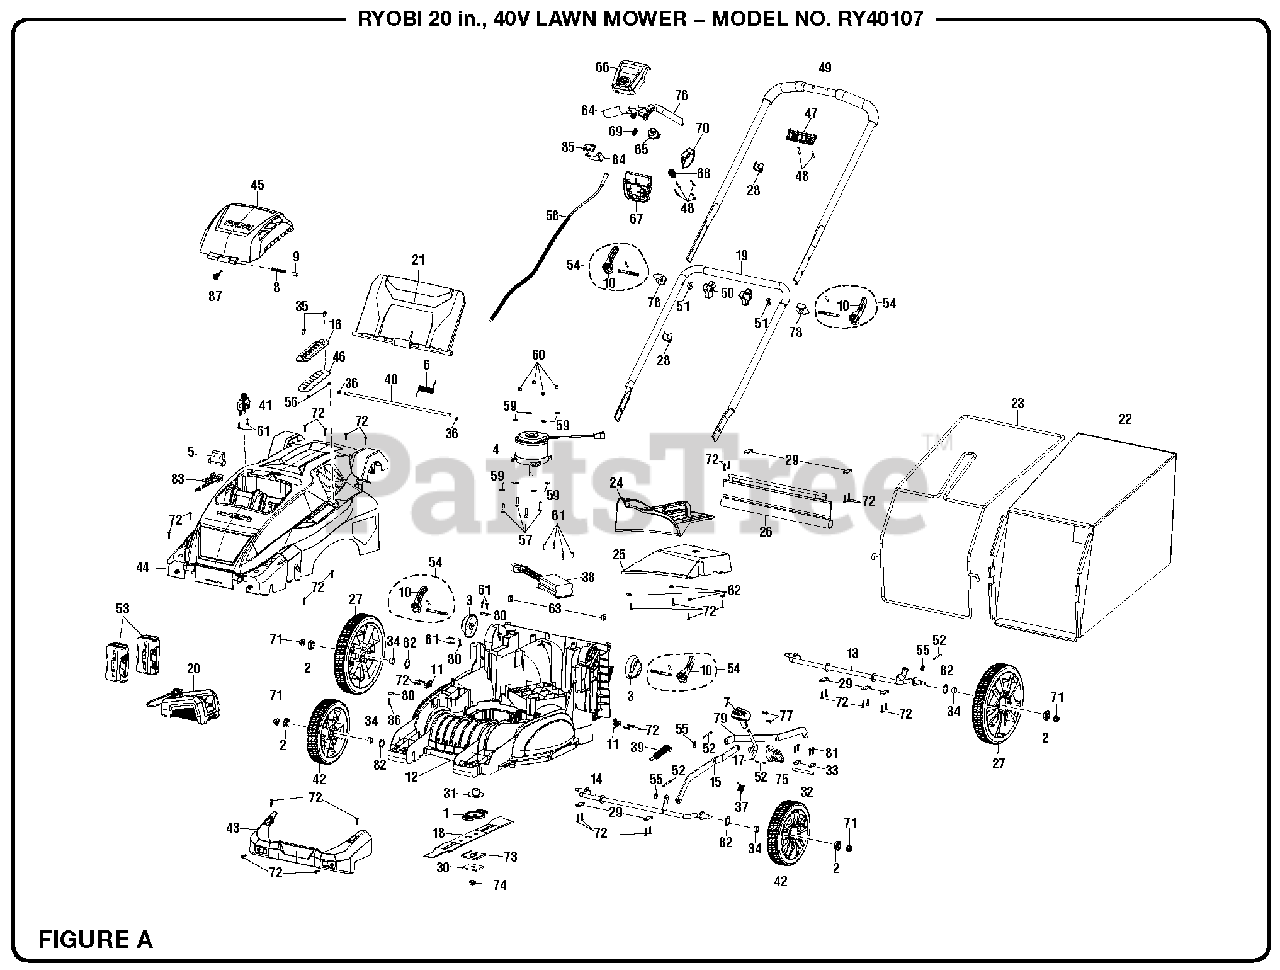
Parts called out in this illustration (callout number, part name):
1	Blade Holder
2	Flanged Outer Ring Bearing
3	Quick Lock Press Block
5	Base (Battery Connect)
6	Torsion Spring (Rear Door)
7	Adjust Height Handle
10	Adjust Height Handle
11	Axle Mount
12	Deck (20 in)
13	Rear Wheel Axle
14	Front Wheel Axle
15	Forward Linkage
16	Lift Arm Bracket
18	Blade
19	Lower Handle
20	Charger
21	Rear Door
23	Bag Frame
24	Mulching Plug
26	Rear Protective Guard
27	Rear Wheel (10 in)
28	Cord Clamp
29	Axle Press Plate
30	Metal Blade Retainer
31	Motor Shaft Bushing
32	Adjust Height Axle
33	Adjust Height Press Plate
34	Bearing Sleeve
35	Screw (M5 x 16 mm, Phillips Pan Hd)
36	Retaining Ring (E)
37	Torsion Spring (Height Adjustment)
38	Electical Control Panel Assembly
39	Retention Spring
40	Rear Door Axle
42	Front Wheel (8 in)
44	Deck Cover
45	Battery Cover
46	Shifter Boot
47	Lower Front Control
48	Screw (M4 x 30 mm, T15 Torx Pan Hd)
49	Handle Assembly Upper
52	Cotter Pin
53	Battery
54	Handle Lock Assembly
55	Washer (ID84 x OD18 x 1t)
56	Hex Nut (M5)
57	Bolt (M6 x 26 mm, Hex Hd)
58	Starter Cable
59	Washer (ID15 x OD62 x 08t)
60	Hex Nut (M6)
61	Screw (M4 x 16mm, T20 Torx Hd)
62	Washer (ID45 x OD10 x 1t)
63	Square Nut (M8)
64	Trigger (Right)
65	Safety Button
66	Front Housing
67	Rear Housing
68	Handle Adjustment Spring
69	Trigger Spring
70	Switch Holder
72	Screw (M4 x 20 mm, T20 Torx Pan Hd)
74	Blade Nut (M10 x 125 mm)
75	Adjustment Height Bracket
76	Trigger (Left)
77	Screw (M3 x 10 mm)
78	Pressure Block
79	Rearward Linkage
80	Wire Press Plate
81	Screw (M4 x 18 mm, T20 Torx Pan Hd)
82	Wave Washer
83	Circuit Board Assembly
86	Screw (M4)
87	Battery Cover Spring
